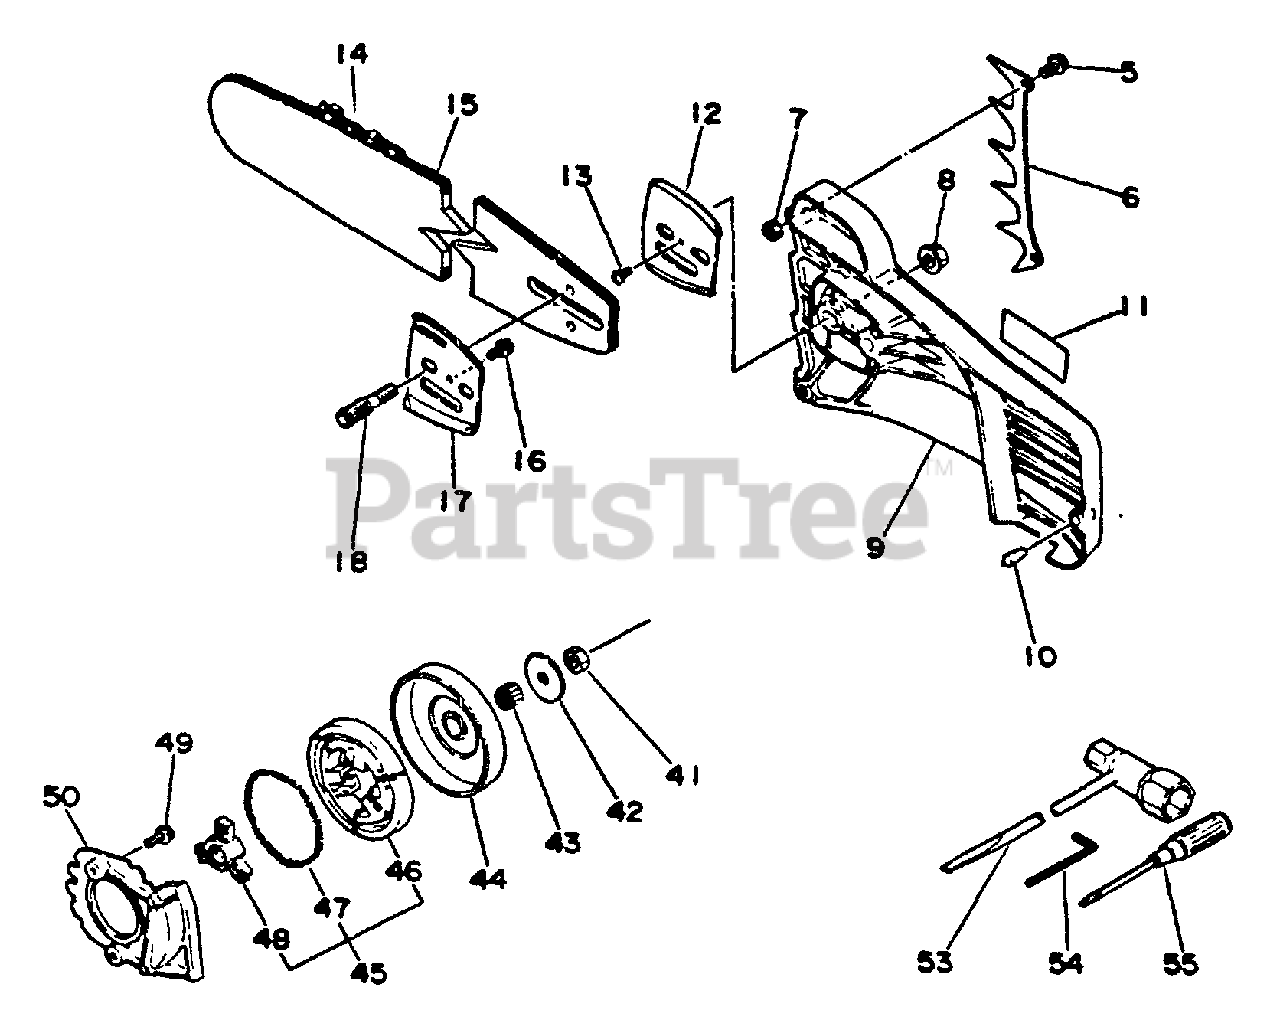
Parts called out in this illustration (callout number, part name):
5	BOLT 5×12
6	SPIKE, BUMPER
7	LOCKNUT - 5
8	NUT, FLANGE M8×1.25
9	GUARD, SPROCKET
10	PIN, DOWEL
11	LABEL - ECHO
12	PLATE, SIDE
13	SCREW 3×6
14	CHAIN
15	GUIDE BAR
16	SCREW 4×10
17	PLATE, SIDE
18	STUD, GUIDE BAR
41	LOCKNUT
42	WASHER, CLUTCH
43	BEARING, NEEDLE
44	DRUM, CLUTCH
45	CLUTCH ASSY
46	SHOE, CLUTCH
47	SPRING, CLUTCH
48	HUB, CLUTCH
49	SCREW 4×14
53	T-WRENCH 13×19×180
54	WRENCH, ALLEN 4 MM
55	SCREWDRIVER, PHILLIPS
